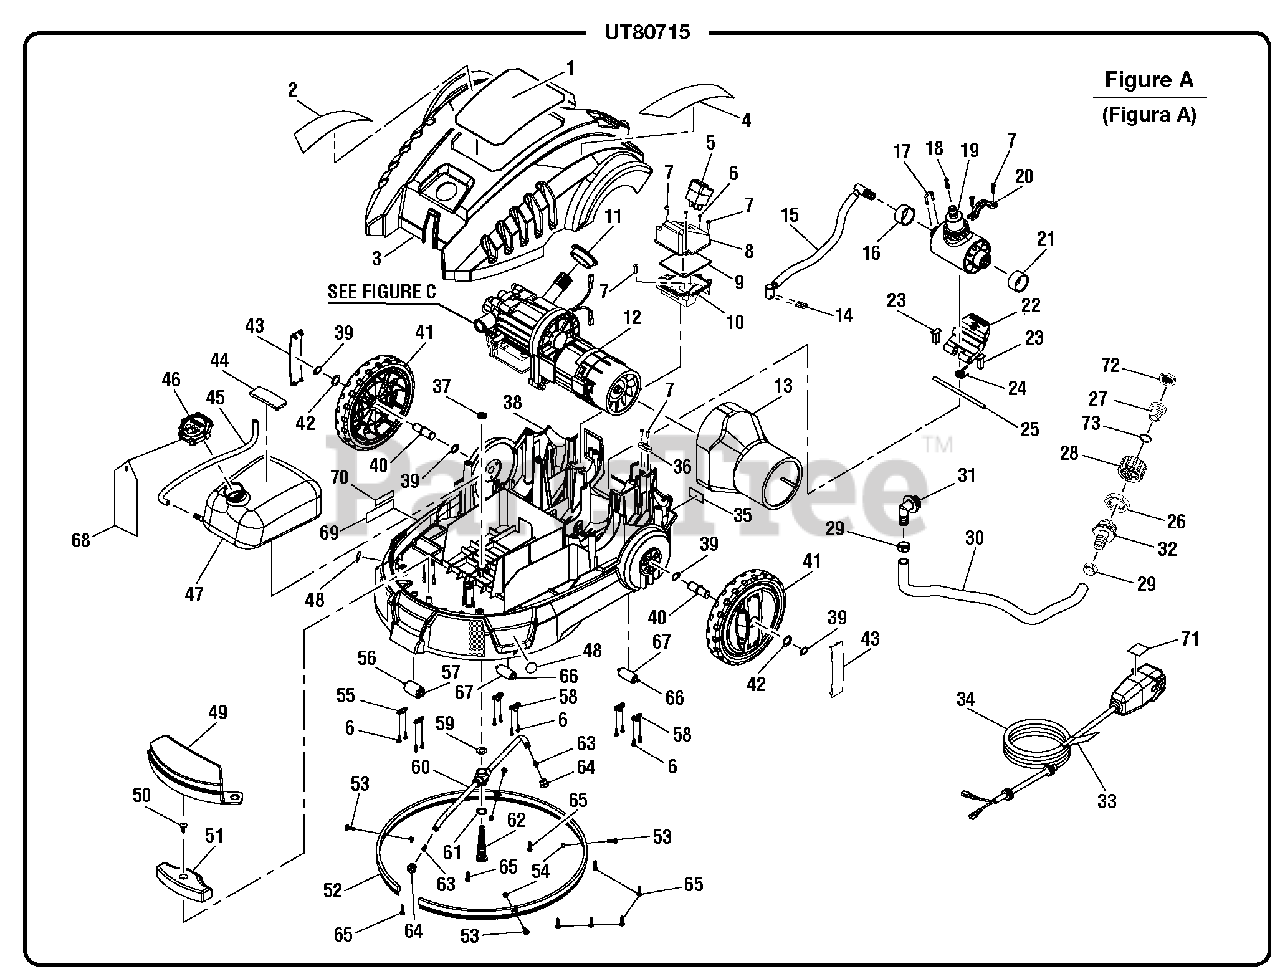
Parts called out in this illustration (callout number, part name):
1	Performance Label
2	Quick Start Label
3	Top Housing Assembly (Incl. Key Nos. 1-2 & 4)
4	Warning Label
6	Screw (M3.5 x 12 mm)
7	Screw (M4.2 x 15 mm)
8	Switch Box Cover
9	Switch Box Gasket
10	Switch Box
11	Pump Outlet Ring
12	Motor and Pump Assembly
13	Motor Baffle
14	U pin (2.5 mm)
15	High Pressure Hose Assembly
16	Left Pivot Bushing
17	U pin (3 mm)
18	Nipple Filter
20	Pivot Clamp
21	Right Pivot Bushing
22	Foot Pedal
23	Bearing Block
24	Torsion Spring
25	Foot Pedal Shaft
27	Water Inlet Screw
28	Water Inlet Screw Nut
29	Hose Clamp
30	Inlet Hose
31	Pump Inlet Connector Assembly
32	Hose Connector
33	Warning Label (UL)
34	Power Cord Assembly (Incl. Key Nos. 33 and 71)
35	Data Label
36	Cord Clamp
37	Spindle Nut (M10)
38	Lower Housing Assembly (Incl. Key Nos. 35 & 48)
39	Retaining Ring
40	Wheel Axle
41	Wheel Assembly
43	Wheel Logo
44	Detergent Tank Pad
45	Detergent Hose
46	Detergent Tank Cap
47	Detergent Tank
48	Foot/Hand Caution Label
49	Lift Handle
50	Screw (M4 x 16 mm)
51	Balast Weight
53	Screw (M4 x 12 mm)
54	Lock Nut (M4)
55	Front Roller Clamp
56	Front Roller Axle
57	Front Roller
58	Rear Roller Clamp
59	Upper Spinner Bushing
60	Spinner Assembly
61	Lower Spinner Bushing
62	Spindle Assembly
63	Spinner Nozzle Assembly
64	Spinner Nozzle Holder
65	Screw (M4.2 x 18 mm)
66	Rear Roller Axle
67	Rear Roller
68	Danger Hangtag
69	Outdoor Use Label (French)
70	Danger Label (French)
71	GFCI Reset Label
72	Water Inlet Filter
73	O-Ring (13.5 x 1.8G)
